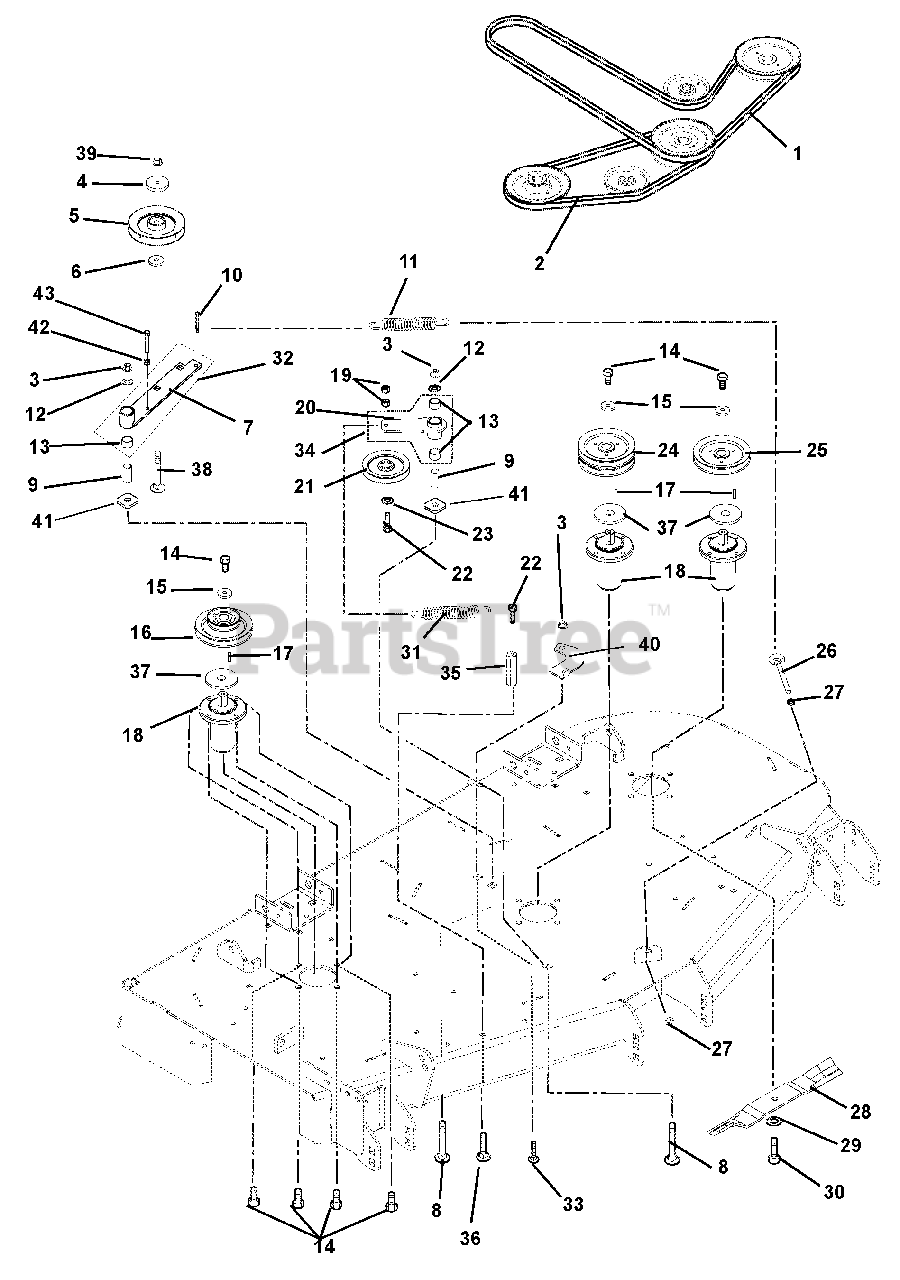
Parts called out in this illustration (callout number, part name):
1	Belt, 144.5" Long, PTO Drive Hex
2	V-Belt, 63" Long Cog B-Section
3	Nut, .50-13 Nyloc Flange
4	Cap, Idler Bearing Sealing
5	Pulley, V 6.0 x .500 ID DBL. Bearing (SN 000101 - 000999)
5	Pulley, V 6.0 x .500 ID SNGL Bearing (SN 001000 and up)
6	Bushing, Spacer .502 x .997 x 0.50
7	Arm, Idler
8	Bolt, Round Head Square Neck .50-13 x 3.50
9	Bushing, Spacer .502 x .997 x 2.03
10	Bolt, Shoulder .38-16 x .30 Hex
11	Spring, Extension
12	Washer, Flat Steel .531x 1.250 x.100
13	Bushing, 1.00 x 1.125 x 1.936
14	Bolt, Hex .38-16 x 1.00
15	Washer, Flat Steel .406 x 1.50 x .245
16	Sheave, Double, 1" ID x 6.75" x 4.35" OD
17	Key, Square .25 x .25 x 1 RC 40-50
18	Spindle Assembly
19	Nut, Locking-Center .38-16
20	Arm, Idler
21	Assembly, V-Idler 5.00 O.D.
22	Bolt, Hex .38-16 x 2.25
23	Washer, Flat Steel .406 x .812 x .065
24	Sheave, Double 1" ID x 6.75" OD
25	Sheave, Single 1" ID x 6.75" OD
26	Bolt, .38-16 x 4.50 .62 Diameter Eye
27	Nut, Hex, Jam .375-16
28	Blade, Mower (20.50")
29	Washer, Bellville .63 x 1.625 x.14
30	Bolt, Hex .62-18 x 1.75 Grade 8
31	Spring, Extension
32	Assembly, PTO Idler Pivot Arm (Includes item # 7 and item # 13)
33	Bolt, Round Head Square Neck .50-13 x 1.5, Full Thread, Grade 5
34	Assembly, Idler Pivot Arm (Includes item # 13 and item # 20)
35	Nut, Coupling .375-16 x 1.75
36	Bolt, Round Head Square Neck .38-16 x 1.00
37	Retainer, Grease
38	Bolt, Round Head Square Neck .50-13 x 3.00 Grade 5
39	Nut, Locking Center .50-13
40	Stop, PM320 PTO Idler Arm
41	Washer, Flat Steel .640 x 1.75 x .250
42	Nut, Hex .38-16
43	Bolt, Hex .38-16 x 2.75
